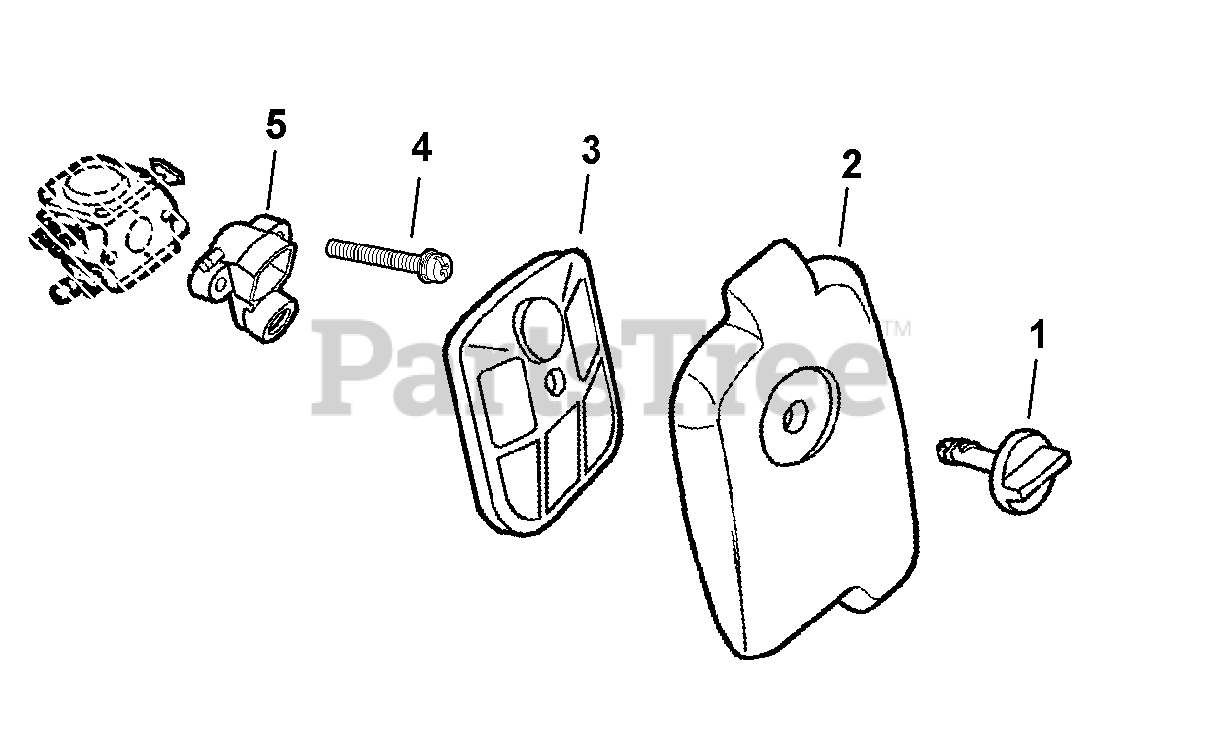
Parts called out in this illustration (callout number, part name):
1	THUMBSCREW
2	COVER, AIR FILTER
3	FILTER, AIR
4	SCREW 5×50
5	ADAPTOR, AIR FILTER
